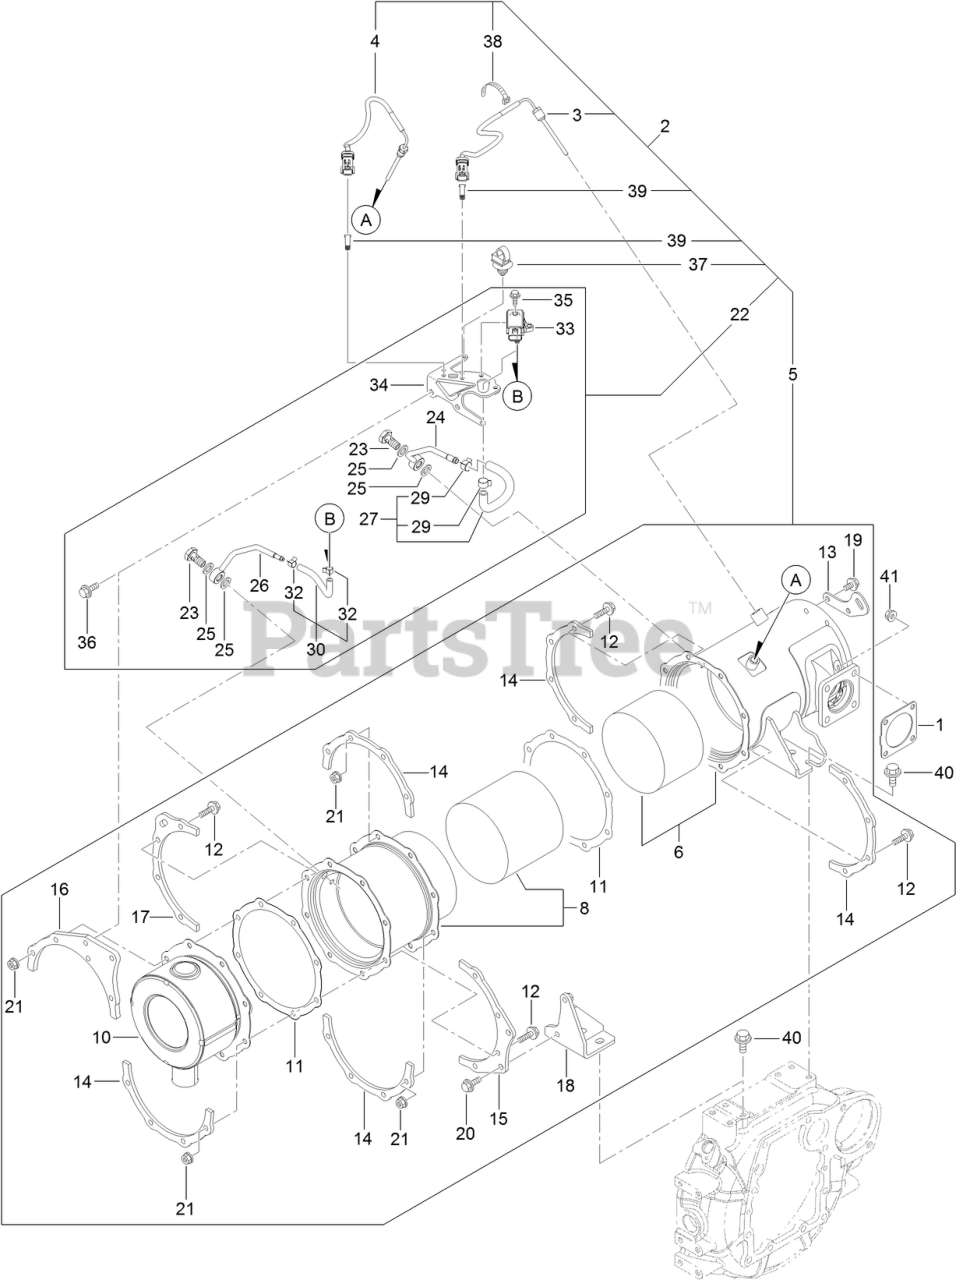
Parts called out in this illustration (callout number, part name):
1	GASKET
2	DPF UNIT
3	SENSOR-TEMP, EXHAUST
4	SENSOR-TEMP, EXHAUST
5	D P F ASM
6	CASE-DOC
8	CASE-SOOT FILTER
10	SILENCER-D P F
11	GASKET-D P F
13	LIFTER-D P F
14	STIFFENER-D P F, A
15	STIFFENER-D P F, B
16	STIFFENER-D P F, C
17	STIFFENER-D P F, C
18	STAY-DPF
22	SENSOR PRESSURE UNIT
23	BOLT-JOINT, PIPE
24	PIPE-SENSOR
25	GASKET-SENSOR
26	PIPE-SENSOR
27	EXHAUST HOSE ASM
29	CLIP-HOSE
30	EXHAUST PRESSURE HOSE ASM
32	CLIP-HOSE
33	SENSOR-PRESSURE
34	BRACKET-SENSOR, PRESSURE
37	BAND-CLIP
39	CLIP-CONNNECTOR
